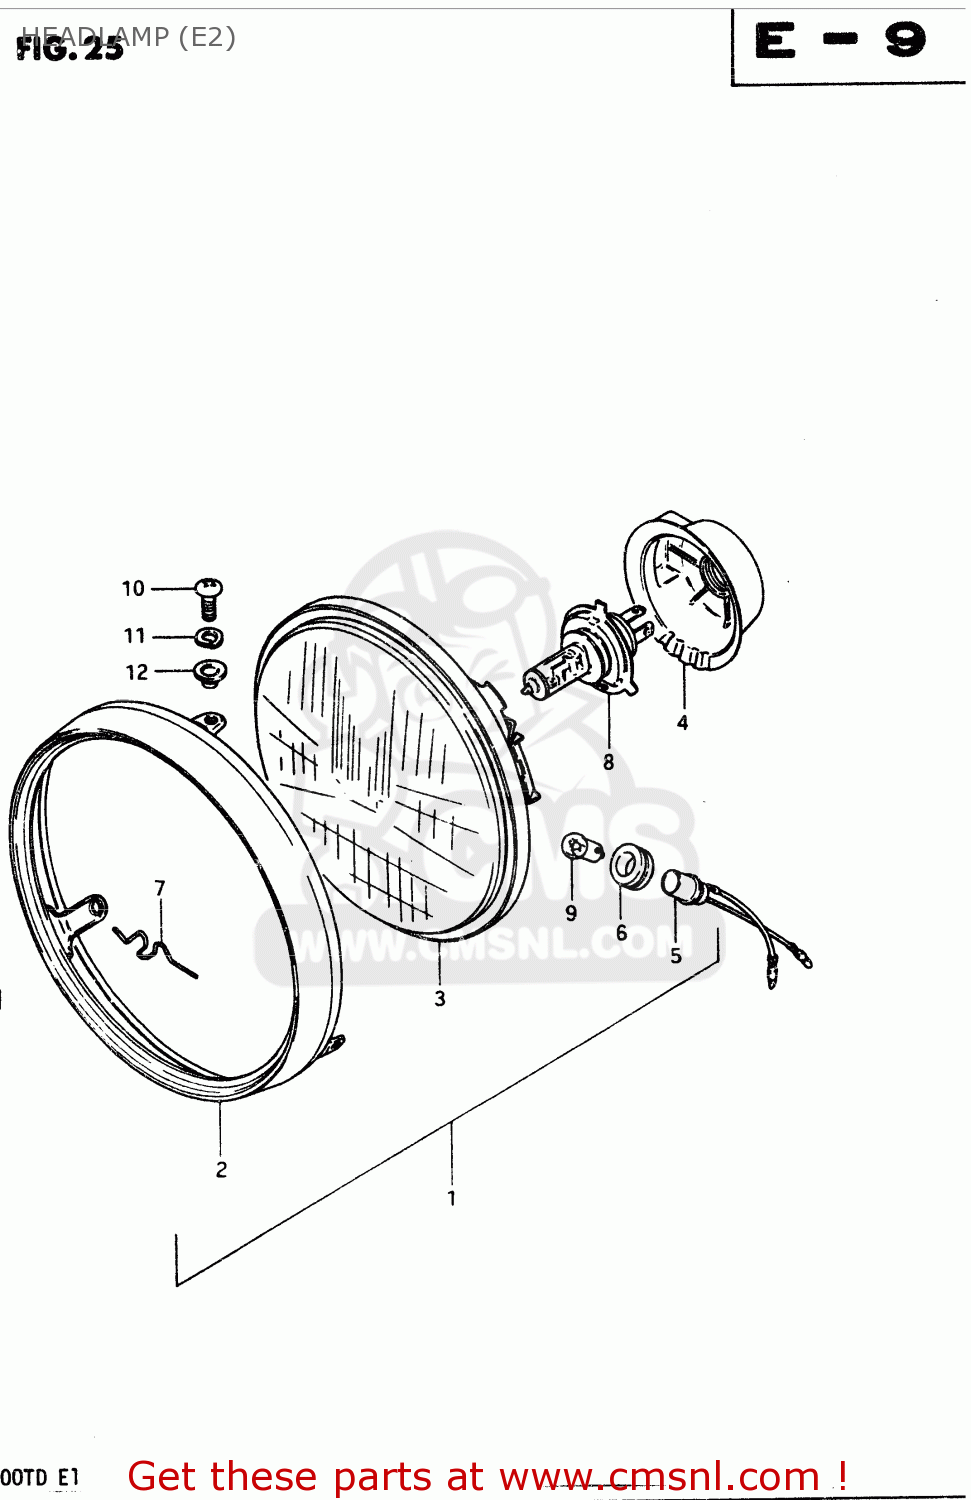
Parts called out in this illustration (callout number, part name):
1	HEADLAMP ASSY
2	RIM
3	LAMP UNIT
4	COVER,SOCKET
5	SOCKET
6	JOINT,RUBBER
7	SPRING
8	BULB(12V60/55W,H4)
9	BULB(12V3.4W,STANLEY,A72A)
10	SCREW
11	WASHER,LOCK
12	WASHER
